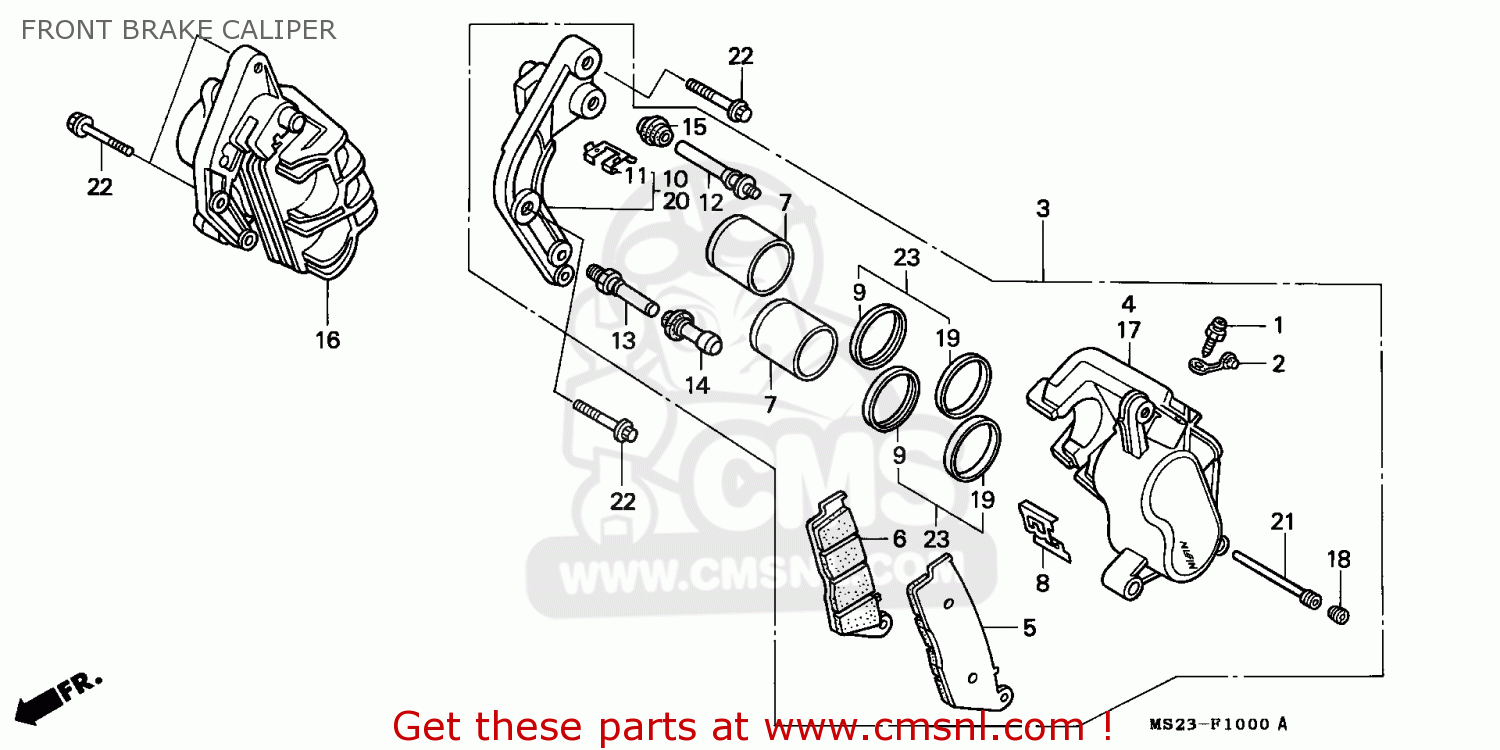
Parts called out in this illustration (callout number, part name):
1	SCREW, BLEEDER
2	CAP,BLEEDER
3	CALIPER ASSY,L FR
4	CALIPER BODY,L.FR
5	PAD COMP.A,FR. (NAS)
6	PAD COMP.B,FR. (NAS)
7	PISTON
8	SPRING,PAD (NISSI
9	DUST SEAL
10	BRACKET COMP,L FR
11	RETAINER,BRKT
12	BOLT A,PIN (NISSI
13	PIN,BOLT
14	BUSH,PIN
15	BOOT B
16	CALIPER ASSY,R,FR
17	BODY,R.FR.CALIPER
18	PLUG,PIN
19	SEAL,PISTON
20	BRACKET COMP.,R.(
21	PIN,HANGER
22	BOLT,FLANGE,DR.8X
